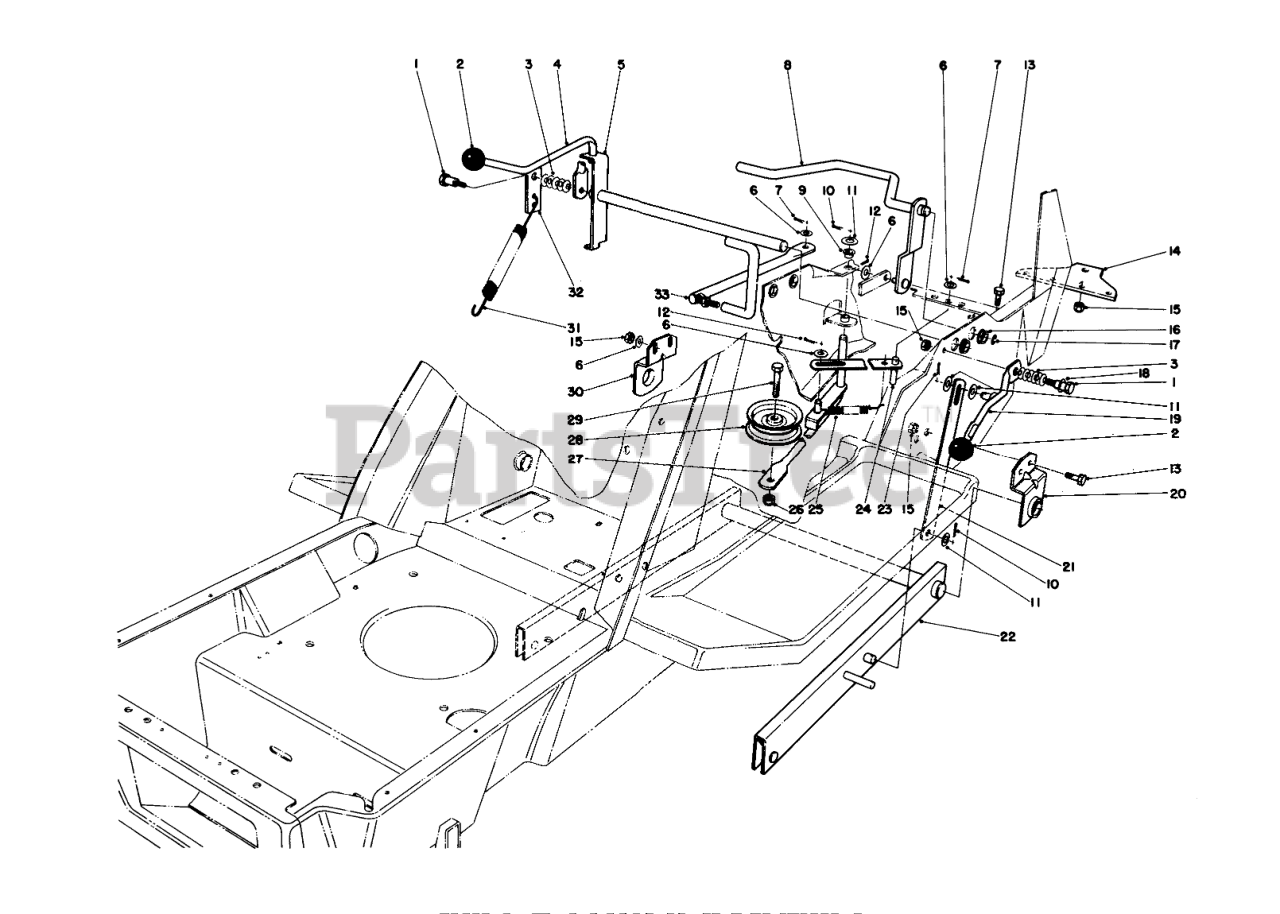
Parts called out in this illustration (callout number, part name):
1	BOLT-SHOULDER
3	WASHER-BELLEVILLE
4	SHIFT LEVER BO
5	Shim Lever
6	WASHER-PLAIN
7	PIN-COTTER
8	CLUTCH ACTUATOR WA B
9	BUSHING-NYLINER
10	PIN-COTTER
11	WASHER-FLAT
12	PIN-COTTER
13	SCREW-HH
14	HITCH PLATE R
15	NUT-LOCK, CONE
16	Nyliner
17	E-RING
18	WASHER-FLAT
19	HOC HANDLE WA B
20	LH PIVOT BAR RET B
21	H.O.C. STRAP B
22	Bar-Pivot
23	PIN-COTTER
24	SPRING RET WA B
25	DECK TENSION SPRNG O
26	NUT-LOCK, CONE
27	IDLER ARM WA BO
28	Pulley-Idler
29	SCREW-HH
30	RH PIVOT BAR RET B
31	TRACTION SPRING
32	BRKT-COBALANCE SPRING
33	SHIFT ARM BO
